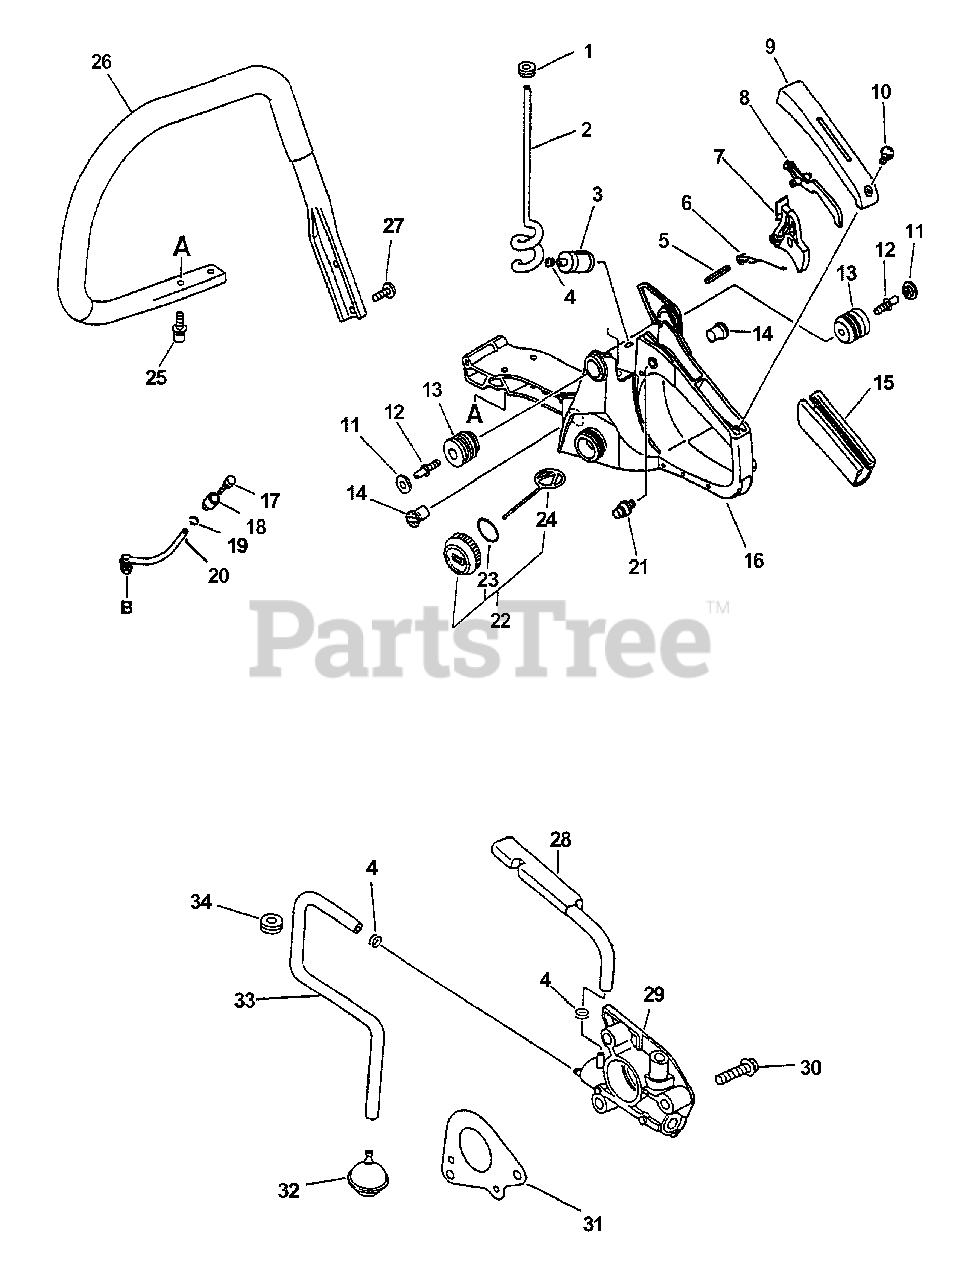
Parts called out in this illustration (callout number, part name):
2	PIPE, FUEL 3×6×165
3	FILTER, FUEL
4	CLIP Ø6.5 MM
5	PIN, SPRING 4×30
6	SPRING, THROTTLE RETURN
7	TRIGGER, THROTTLE
8	LEVER, THROTTLE LOCKOUT
9	COVER, HANDLE
10	SCREW 4×14
11	CAP, CUSHION
13	CUSHION 5
14	CUSHION 5
15	GRIP, HANDLE
16	REAR HANDLE KIT
17	VENT ASSY
18	HOLDER, VENT
19	CLIP Ø6.5 MM
20	PIPE, VENT - GROMMET
21	LATCH, THROTTLE
22	CAP ASSY, FUEL
23	O-RING 22
24	CONNECTOR, CAP L= 60 MM
25	SCREW 5×16
26	HANDLE, FRONT
27	SCREW, TAPPING
28	PIPE, OIL OUTLET
29	AUTO-OILER ASSY
30	SCREW 4×16
31	PLATE, SEAL
32	FILTER, OIL
33	PIPE, OIL
